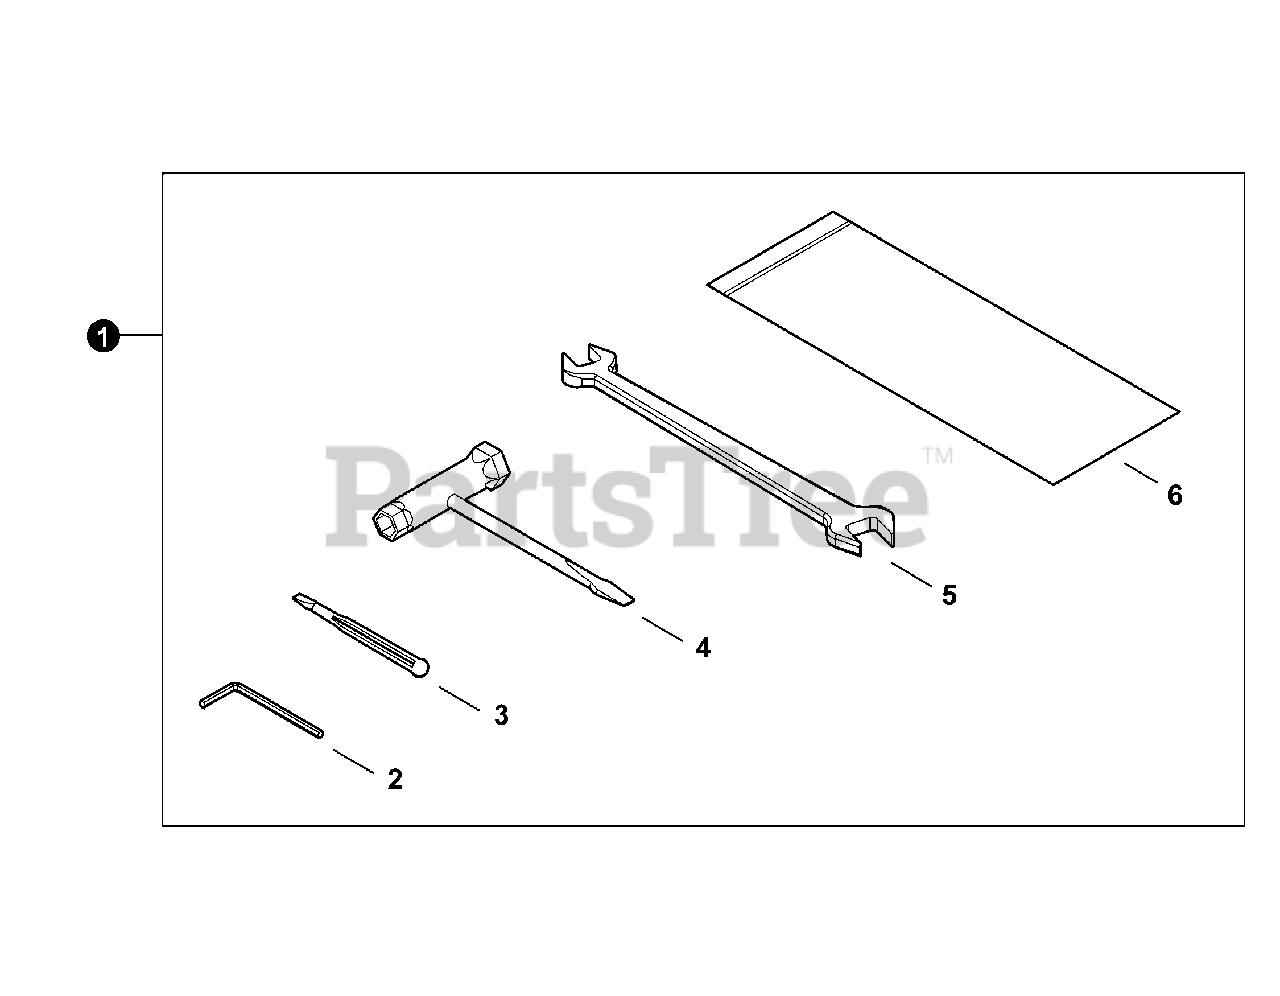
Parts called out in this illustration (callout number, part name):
1	TOOL KIT, SERVICE
2	WRENCH, ALLEN 4MM
3	SCREWDRIVER, PLASTIC
4	T-WRENCH 13×19mm
5	SPANNER 8×10
6	BAG, TOOL
